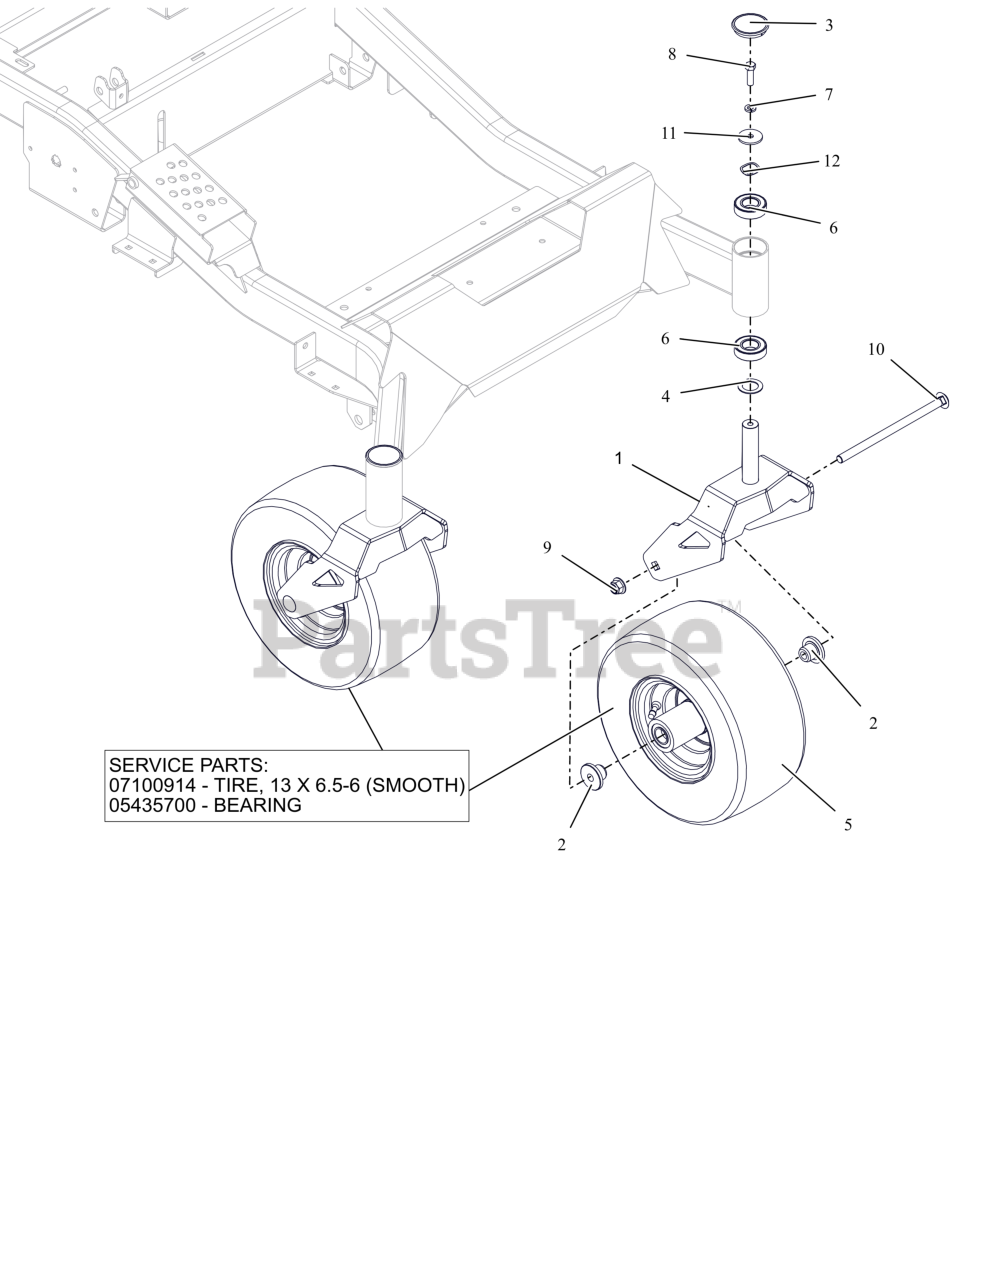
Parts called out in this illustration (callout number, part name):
1	WLDMT, CASTER FORK-APEX (ORANGE)
2	SPACER, FRONT WHEEL
3	CAP, DUST
4	WSHR-HRD-THRS 1.007X1.542X.062
5	ASM, WHL/TIRE 13X6.50-6
5	TIRE, 13X6.50-6 SMOOTH
5	BRG, 25MM ID X 52MM OD X 15MM
6	BRG,BALL 1.00X2.00X.563(1641)
7	WSHR, LK-HVY .375X.115 ZCC
8	BLT, HEX .38-16X1.25 G5 ZCC
9	NUT,NYL-FLG .50-13 GF ZCC
10	BLT, RHSN .50-13X9.00 G5 ZCC
11	WSHR, FLT .380X1.50X.125 ZCC
12	WSHR-WAVE 1.0X1.25X.028 .145FH
